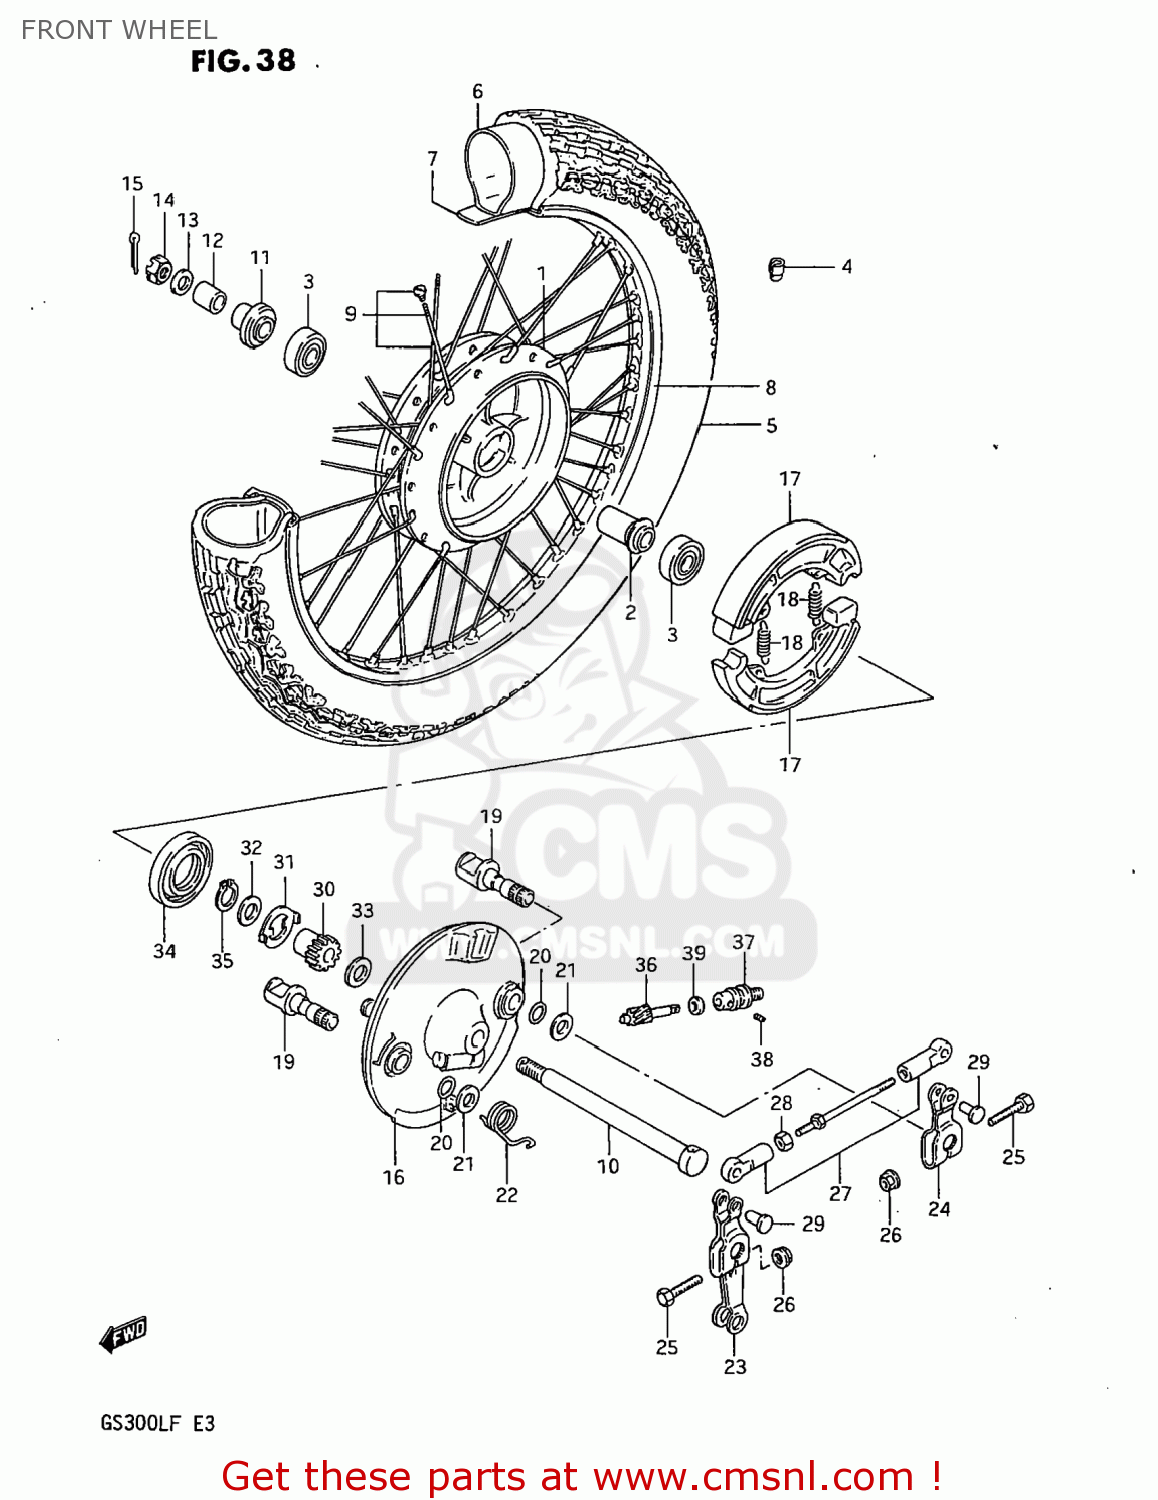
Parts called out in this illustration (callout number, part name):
1	HUB,FRONT
2	SPACER,FRONT HUB BEARING
3	BEARING
4	BALANCER,WHEEL (B)
5	TIRE
6	TUBE,INNER
7	PROTECTOR,INNER TUBE
8	RIM,FRONT WHEEL
9	SPOKE SET,FRONT
10	AXLE,FRONT
11	SPACER,FR AXLE,R
12	SPACER(15X22X30)
13	WASHER
14	NUT 12MM
15	COTTER PIN
16	PANEL,FRONT HUB
17	SHOE,BRAKE
18	SPRING,BRAKE SHOE
19	CAM,FRONT BRAKE
20	O-RING,BOSS
21	WASHER (15X24X1.6)
22	SPRING
23	LEVER,FRONT BRAKE CAM NO
24	LEVER,FRONT BRAKE CAM NO
25	BOLT
26	NUT
27	SHOE SET,BRAKE
28	NUT
30	GEAR,SPEEDOMETER
31	DRIVER,SPEEDOMETER GEAR
32	WASHER(22.5X27X1)
33	SHIM
34	OIL SEAL
35	CIRCLIP
36	PINION,SPEEDOMETER
37	BUSH,METER GEAR OUTER
38	SCREW
39	WASHER (5.1X9X0.4)
